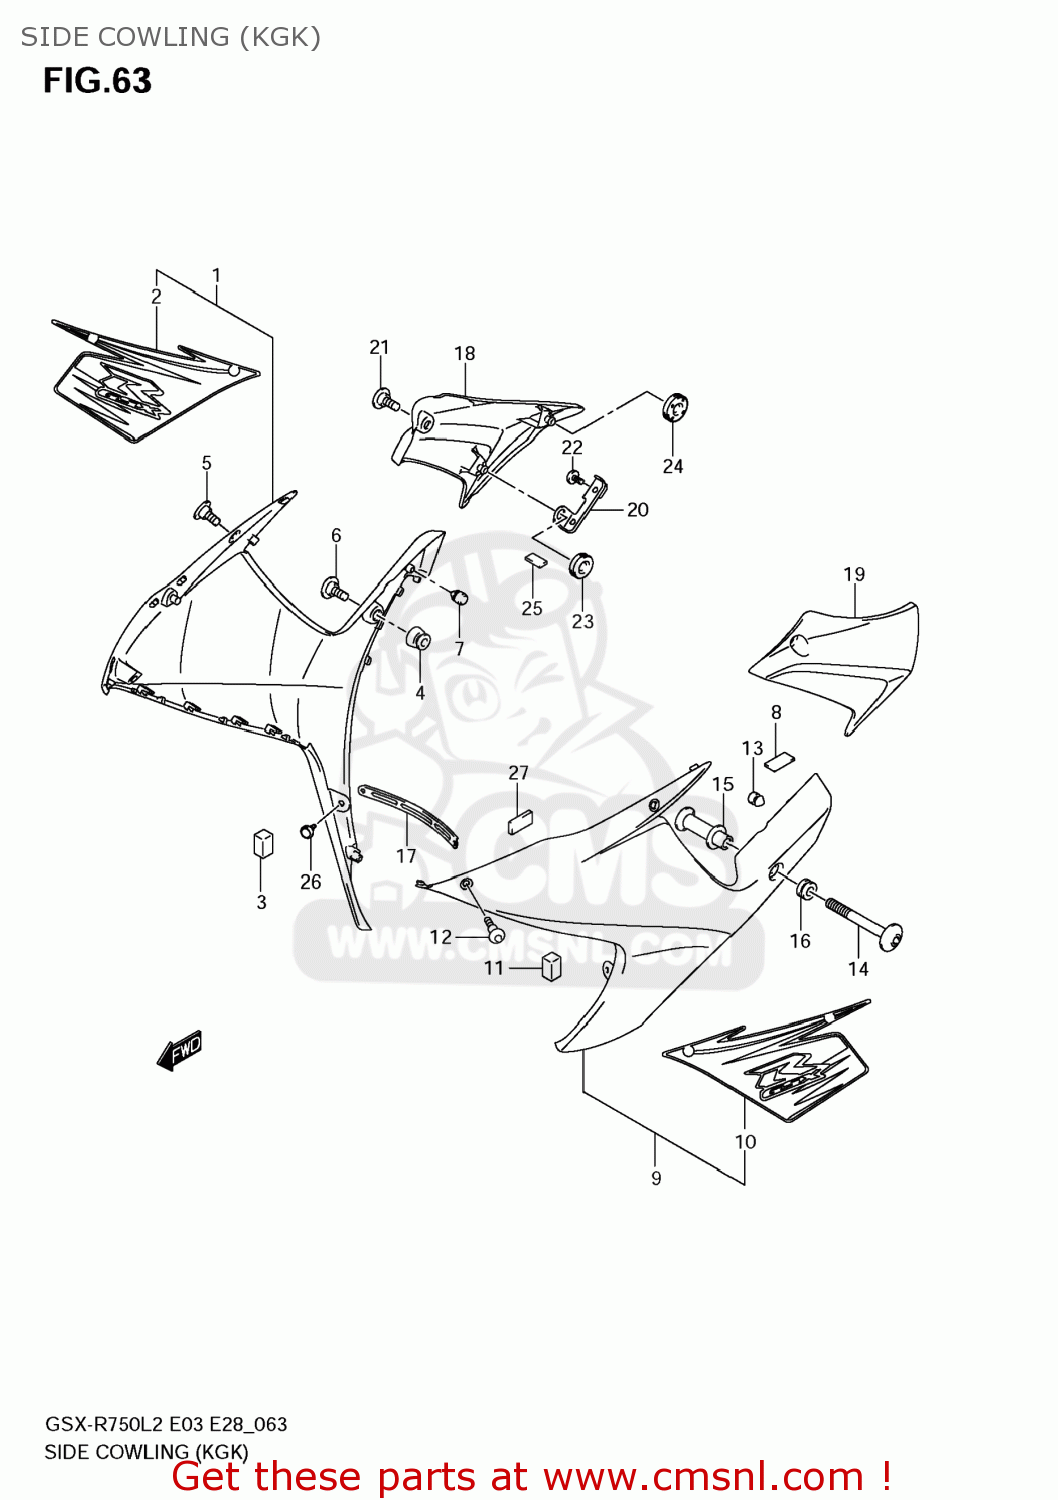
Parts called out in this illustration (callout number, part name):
1	COWLING,SIDE,R(YELLOW)
2	TAPE,SIDE COWLING,R
3	CUSHION,SIDE COWL FR
4	CUSHION,UNDER COWLING,L
5	SCREW(5X13)
6	BOLT(6X20)
7	CUSHION
8	CUSHION,FUEL TANK NO.2
9	COWLING,SIDE,L(YELLOW)
10	TAPE,SIDE COWLING,L
11	CUSHION,SIDE C
12	SCREW(5X13)
13	CUSHION
14	SCREW,SIDE COWL,L
15	SPACER,SIDE COWL,L
16	CUSHION
17	PLATE,UNDER COWL CTR
18	COVER,SIDE COWLING,R
19	COVER,SIDE COWLING,L
20	BRACKET,COVER SIDE,R
21	SCREW(5X13)
22	SCREW(6X12)
23	CUSHION
24	CUSHION
25	CUSHION
26	CLIP
27	PROTECTOR(30X80X1)
